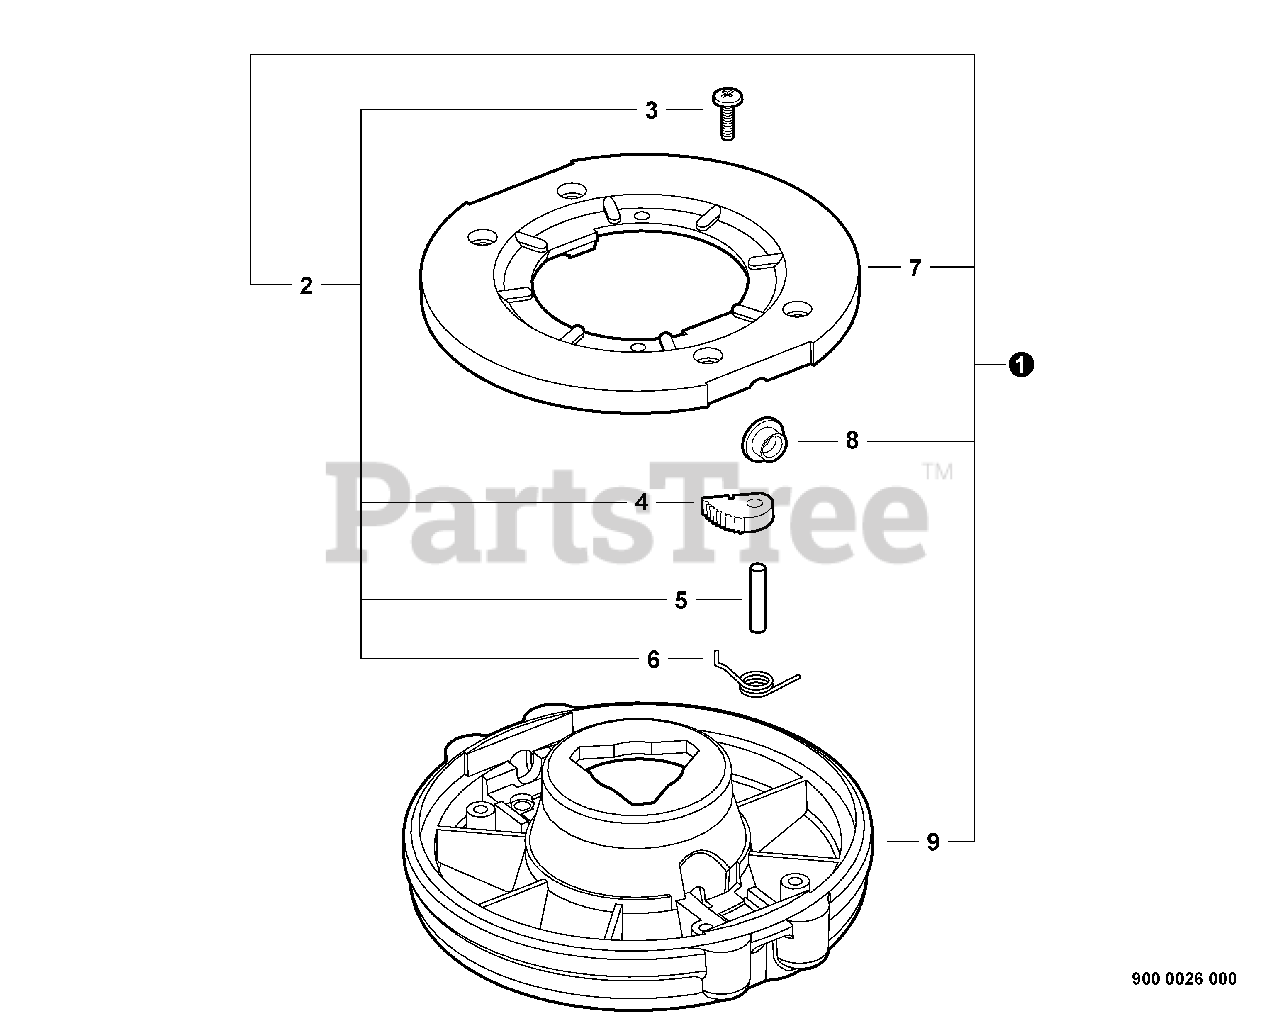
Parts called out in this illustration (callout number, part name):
1	TWO LINE RAPID LOADER HEAD
2	REPAIR KIT
3	SCREW
4	CAM
5	SHAFT
6	SPRING
7	COVER - TOP
